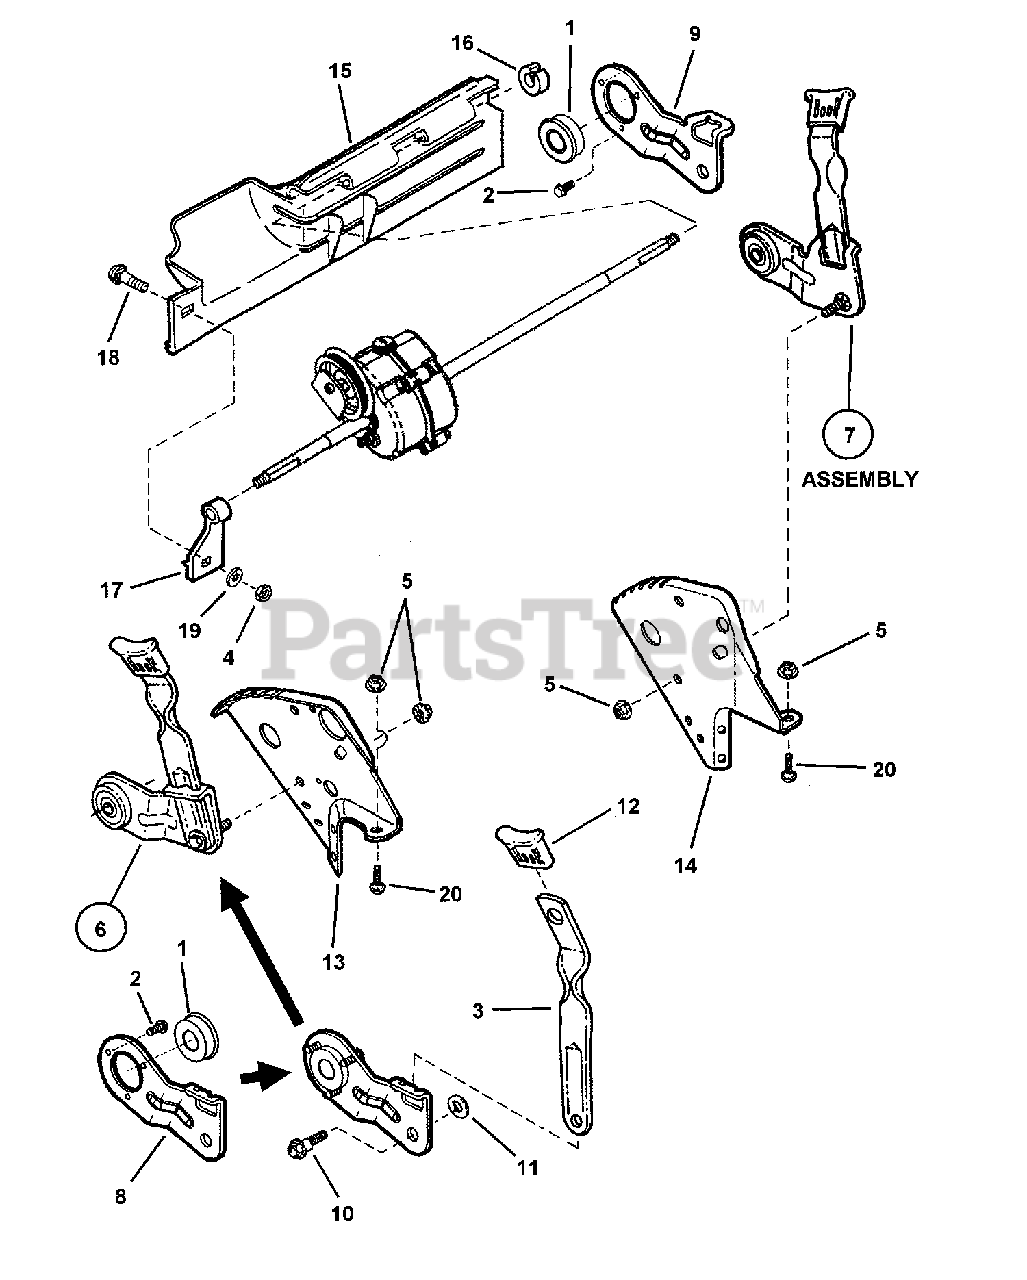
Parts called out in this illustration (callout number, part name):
1	BALL BEARING, 9/16" I.D.
2	SCREW, #10-32 x 3/8" Hex Washer Self-Tap (Torx)
3	LATCH, Height Adjusting (Long)
4	NUT, 1/4-20 Hex
5	NUT, 5/16-18 Hex Flange Lock, GR5
6	ASSEMBLY, Wheel Arm (Right Rear)
7	ASSEMBLY, Wheel Arm (Left Rear)
8	ARM, Wheel, Right Rear
9	ARM, Wheel, Left Rear
10	BOLT, 5/16-18 x 1" Shoulder
11	RETAINER, 5/16" Bolt
12	GRIP, Latch
13	BRACKET, Right Rear Wheel
14	BRACKET, Left Rear Wheel
15	GUARD, Rear Foot
16	RING, Split (Black)
17	SUPPORT, Foot Guard
18	BOLT, 1/4-20 x 1/2" Short Neck Carriage GR5
19	WASHER, 1/4" Internal Tooth Lock
20	BOLT, 5/16-18 x 1/2" Short Neck Carriage GR5
